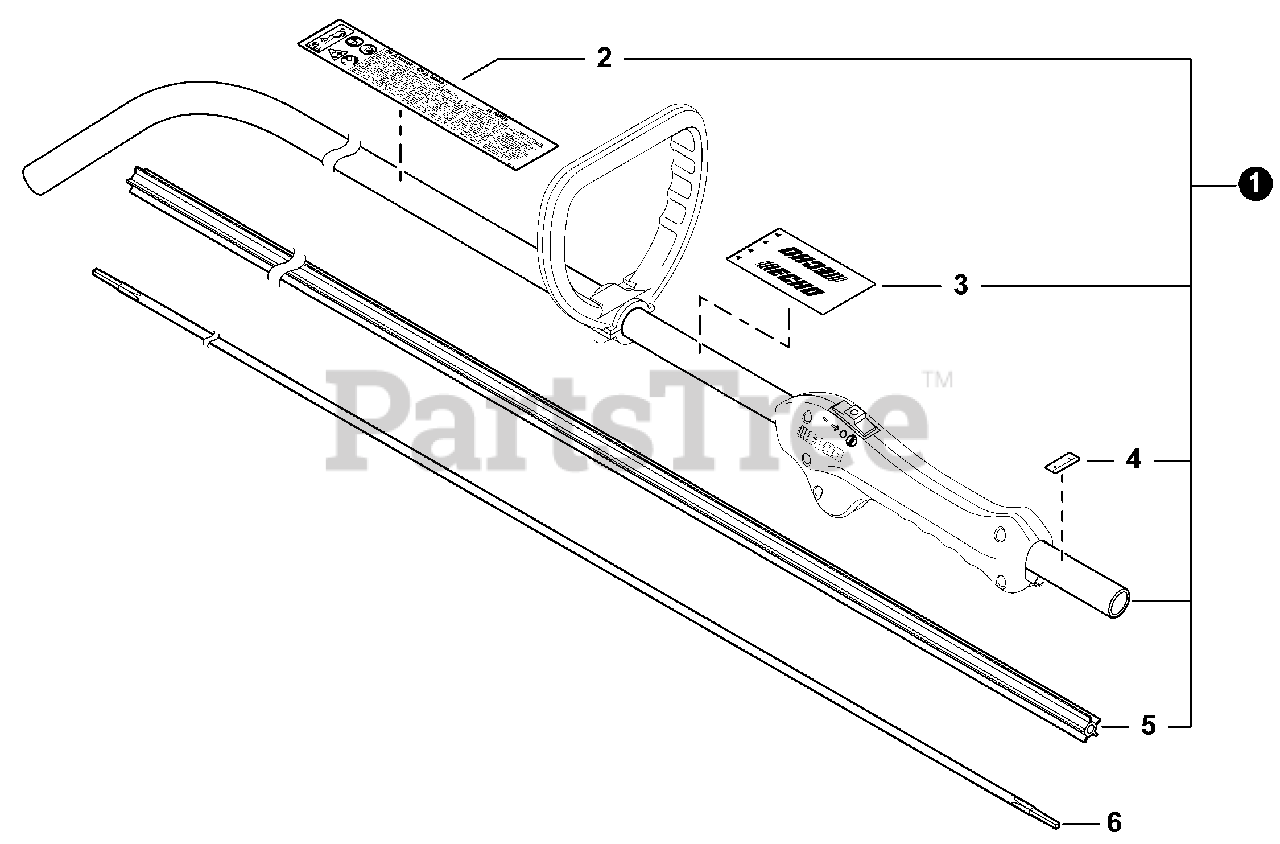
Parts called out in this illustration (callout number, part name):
1	PIPE, MAIN
2	LABEL, CAUTION
3	LABEL, HANDLE LOCATION
4	LABEL - ALIGNMENT
5	LINER - FLEXIBLE
6	DRIVESHAFT - FLEXIBLE
